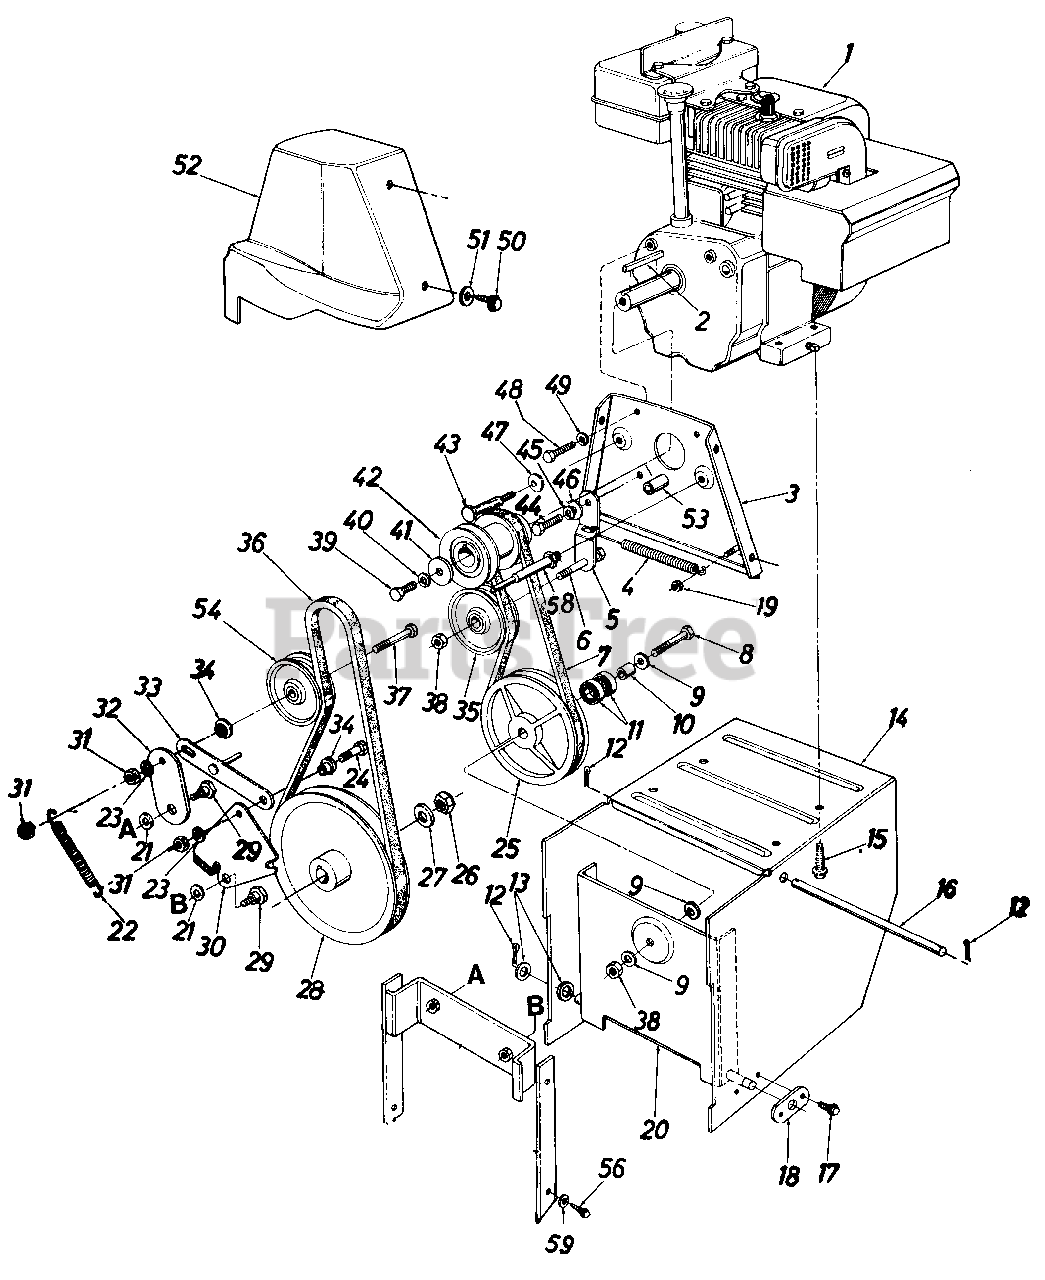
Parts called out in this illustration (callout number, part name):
1	Engine
2	Sq. Key 3/16" x 1.50" Lg.
2	Sq. Key 1/4n x 2.0" Lg.
3	Engine Plate Ass'y.
4	Extension Spring .50" O.D. x 3.97" Lg.
5	Drive Clutch Idler Brkt.
6	Hex Bolt 3/8-24 x 1.25" Lg.
7	V-Belt
8	Hex Bolt 3/8-24 x 1.50" Lg.
9	Bell-Wash. .40" I.D. x .88" O.D. x .06
10	Spacer .38" I.D. x .62" O.D. x.75" Lg.
11	Ball Brg. .62" I.D. x 1.38" O.D. x .44
12	Cotter Pin 3/32" Dia. x .75" Lg.
13	Fl-Wash. .53" I.D. x 1.00" O.D. x .125
14	Frame Ass'y.
15	Hex Wash. Hd. Self-Tap Scr. 3/8-16 x 1.25" Lg.
16	Shaft .50" Dia. x 9.50" Lg.
17	Hex Wash. Hd. Self-Tap Scr. 1/4-20 x .50" Lg.
18	Axle Bracket
19	Hex L-Nut 1/4-20 Thd.
20	Drive Pulley Support Brkt. Ass'y.
21	Bell-Wash. .40" I.D. x 1.13" O.D.
22	Extension Spring .56" O.D. x 4n Lg.
23	L-Wash. 3/8" I.D.
24	Hex Scr. 3/8-16 x 1.25" Lg.
25	6.00" O.D. Drive Pulley Ass'y.
26	Hex Jam Cent. L-Nut 5/8-18 0 Thd.
27	Fl-Wash. .64" I.D. x .94" O.D. x .06
28	1/2" V-Pulley .625" I.D. x 7.50" O.D.
28	5/8" V-Pulley .625" l.D. x 7.50" O.D.
29	Shld. Bolt .625" Dia. x .170" Lg. (3/8-1 6)
30	Brake Bracket Ass'y.
30	Brake Brkt. Ass'y.
31	Hex Ins. L-Nut 3/8-16 Thd.
32	Auger Clutch Idler Brkt.
33	Brake Linkage Ass'y.
34	Shld. Spacer .625" I.D.
35	Fl-ldler Pulley 2.25" O.D.
36	V-Belt
37	Hex Bolt 3/8-16 X 2" Lg.
38	Hex Ins. Jam L-Nut 3/8-24 Thd.
39	Hex Bolt 3/8-24 X 1.50" Lg.
40	L-Wash. 3/8" I.D.
41	Bell-Wash. .40" I.D. x 1.25" O.D.
41	Bell-Wash . .345" I . D. x .88" O.D.
42	Double Groove Engine Pulley
43	Shld. Scr. .498" X 3.0" Lg.
43	Stud 3/8-16 X 3.37" Lg.
44	Hex Bolt 5/16-24 X 1.00" Lg.
45	L-Wash. 5/16" I.D.
46	Shld. Spacer .27" Lg.
47	Bell-Wash. .40" I.D. x .88" x .06
48	Hex Bolt 5/16-24 X .62" Lg.
49	L-Wash. 5/16" I.D.
50	Hex Wash. Hd. Self-Tap Scr. 1/4-20 X .50" Lg.
51	Fl-Wash. .28" l.D. x .75" O.D. x .06
52	Belt Cover
53	Spacer
54	Fl-ldler Pulley 2.75" O.D.
56	Hex Wash. Hd. Self-Tap Scr. 3/8-16 X .75n Lg.
58	Stud 3/8-16 X 3.37n Lg.
59	L-Wash. 3/8" l.D.-H.D.
